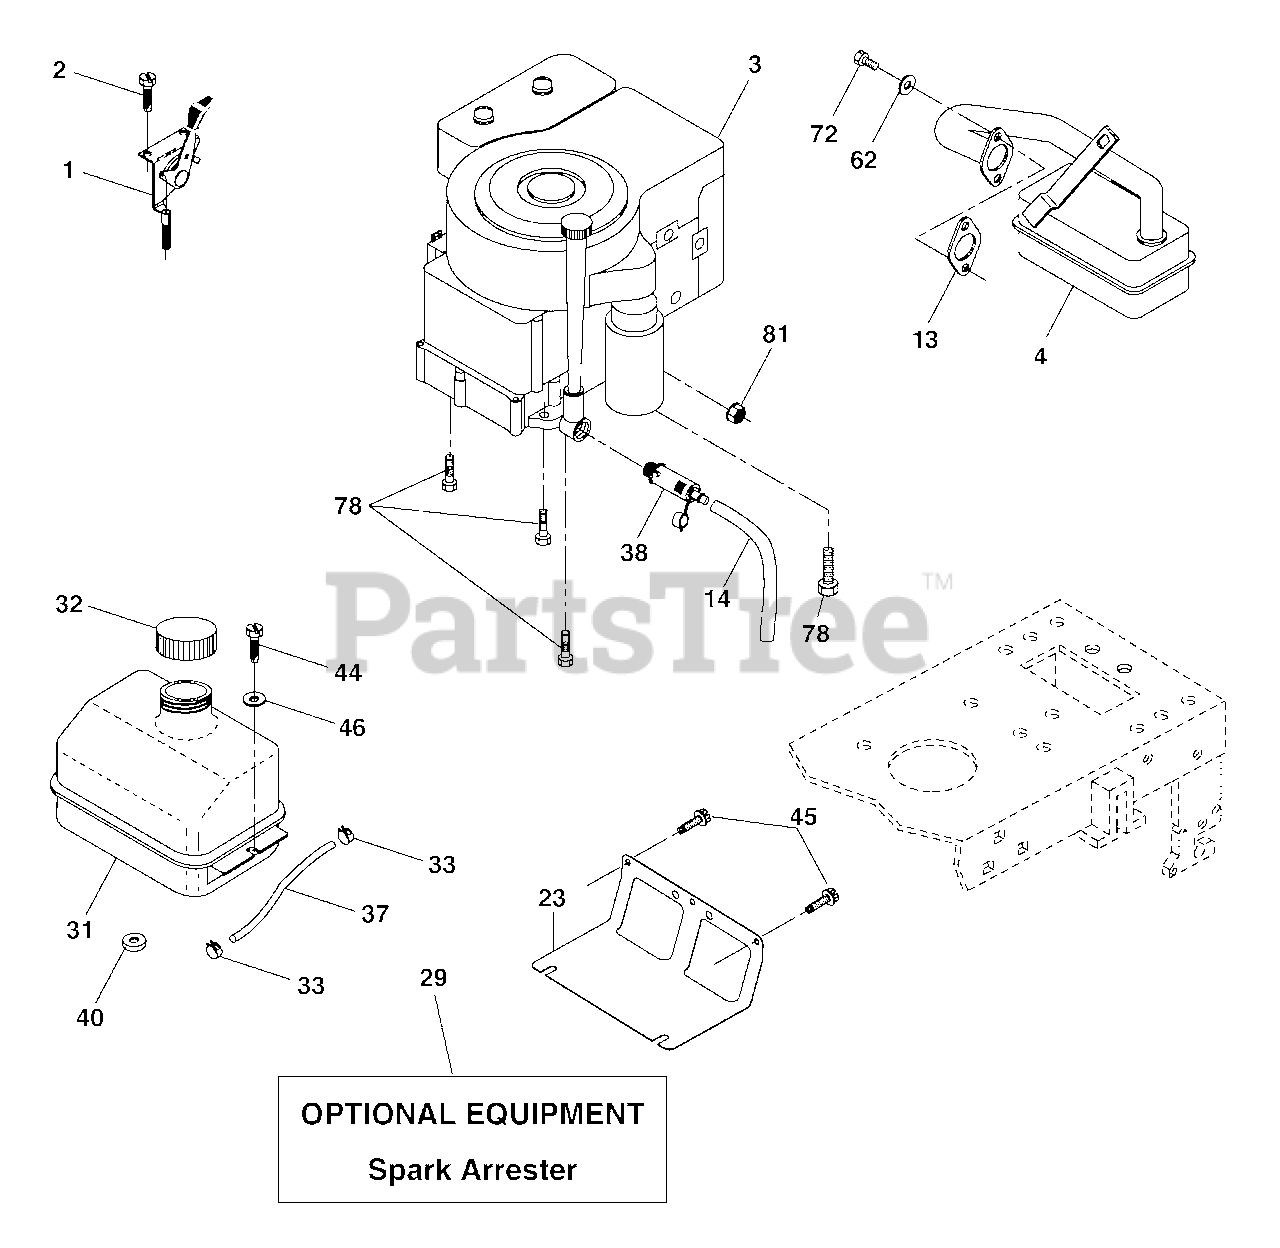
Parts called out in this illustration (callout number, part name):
1	Control, Throttle
2	Screw Hex Thd Cut 1/4-20 x 1/2
4	Muffler
13	Muffler Gasket
14	Tube Oil Drain
23	Shield, Browning/Debris Guard
29	Arrester, Spark
32	Cap, Fuel
33	Clamp, Hose Blk
37	Line, Fuel
38	Plug Drain Oil Easy
40	Bushing
44	Screw Hex Wsh THDROL 1/4-20 x 3/4
45	Screw Hex Wsh Thdrol 3/8-16 x 3/4
46	Washer 9/32 x 7/8 x 16 Ga.
62	Washer Split
72	Screw Hex Hd Cap 5/16-18 x 3/4
78	Screw 3/8-16 x 1-1/4
81	Nut Keps Hex 1/4-20 unc
